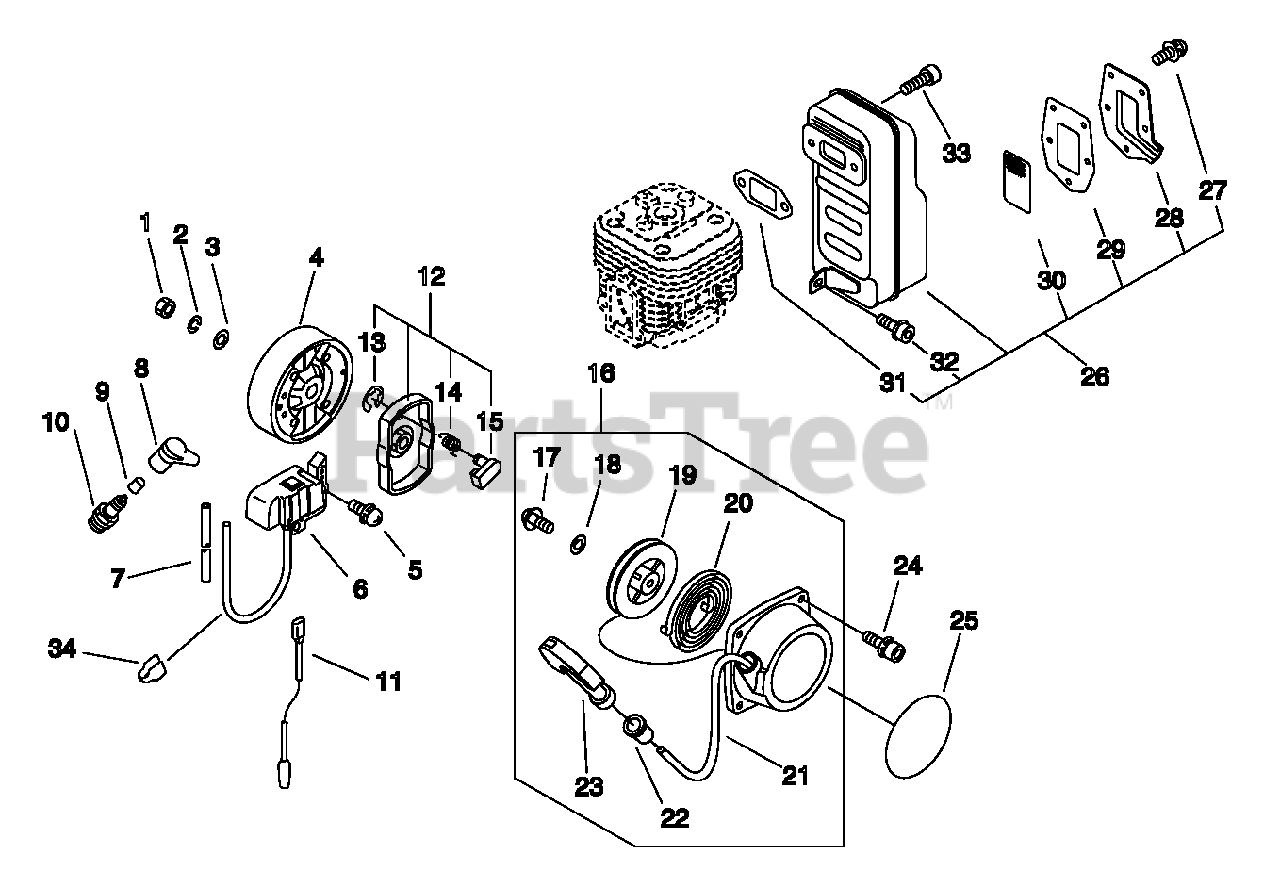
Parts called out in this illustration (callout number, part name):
2	WASHER, SPRING 10
3	WASHER, SPRING 10
4	FLYWHEEL
5	SCREW 5×18
6	COIL, IGNITION
7	TUBE, VINYL 6.3×8×380
8	CAP, SPARK PLUG
9	TERMINAL, SPARK PLUG
10	SPARK PLUG - BPMR8Y
11	LEAD - IGNITION
12	PAWL ASSY, STARTER
13	E-RING 4
14	SPRING, RETURN
15	PAWL, STARTER
16	STARTER ASSY, RECOIL
19	REEL, ROPE
20	SPRING, RECOIL
21	ROPE, STARTER 3.8×1400
22	GUIDE, ROPE
23	GRIP, STARTER
24	BOLT 5×18
25	LABEL, ECHO
26	MUFFLER ASSY
27	SCREW 4×10
28	GUIDE, EXHAUST
29	GASKET, EXHAUST
30	SCREEN, SPARK ARRESTER
31	HEAT SHIELD, EXHAUST
32	BOLT 5×16
33	BOLT 6×20
34	LABEL, SPARK PLUG - BPM8Y
